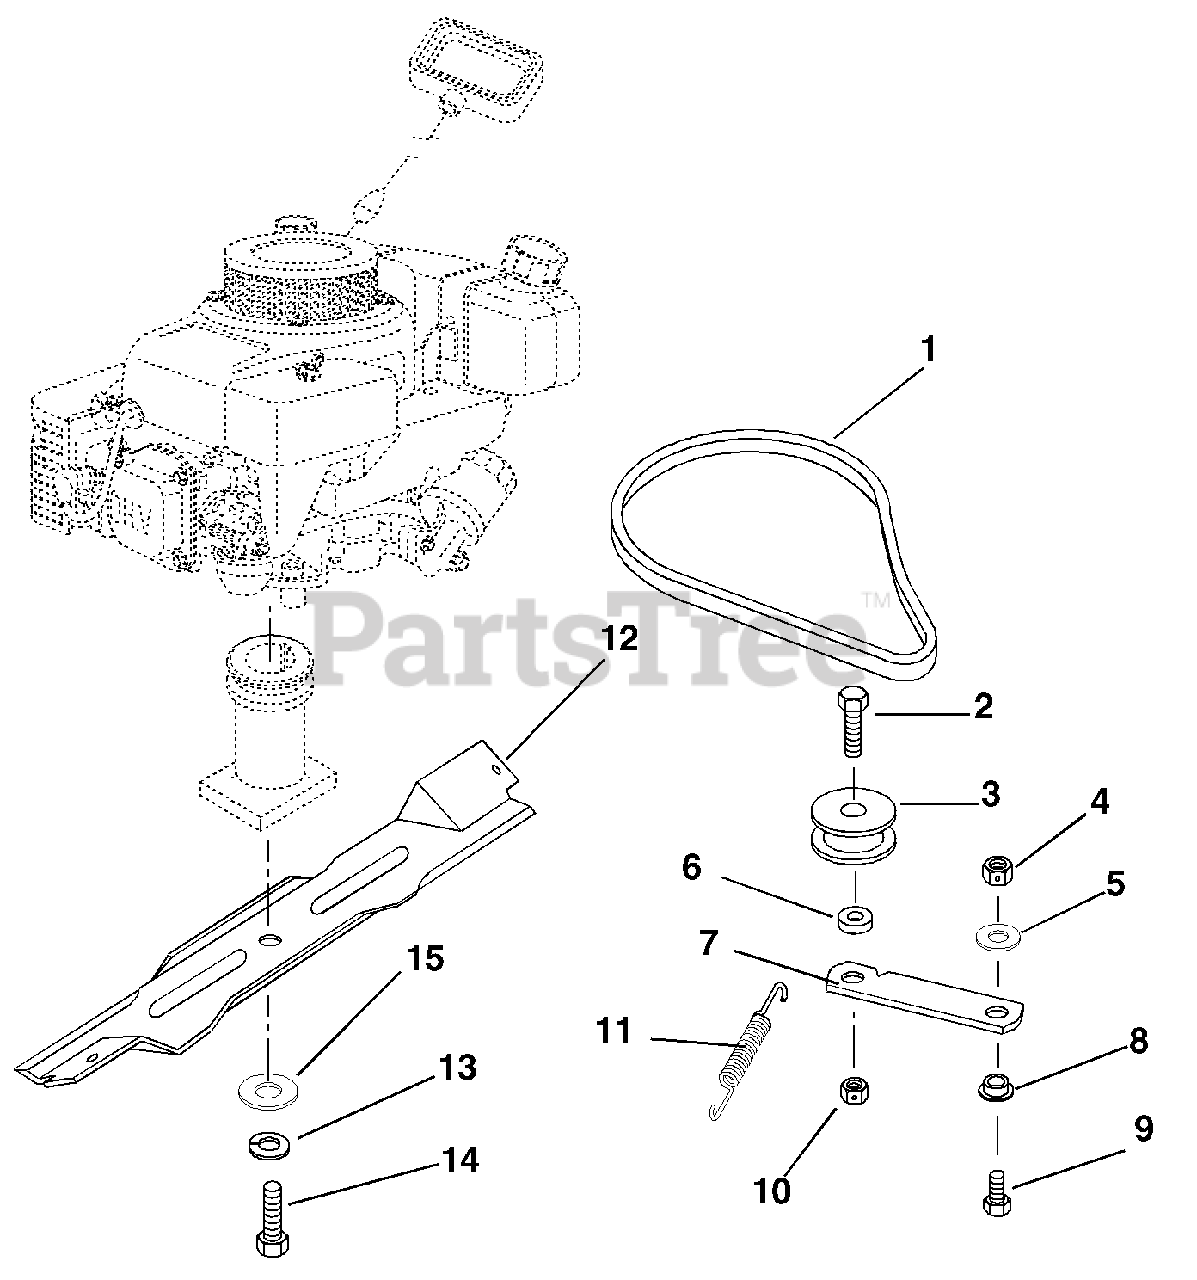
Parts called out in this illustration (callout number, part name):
1	V-BELT, 3L-COGGED
2	@BLT-HEX .44-14X1.25 GR5 YWZC
3	IDLER-FLAT 1.75 X .47
4	@NUT-LK-CTR .31-18 YWZC
5	WSHR-FL-STL .323X.625X.062 YWZ
6	SPACER .52 X .45 X .34
7	IDLER ARM
8	BSHG-FLG .325X.501X.250X1.120
9	@BLT-HEX .31-18X.75 GR5 YWZC
10	@NUT-LK-CTR .44-14 YWZC
11	SG-TENS .043X.44X3.31 WLD 5.8
12	BLADE LM 21 IN
13	@WSHR-LK .38X.094 REG YWZC
14	BLT-HEX .38-24 X 2.00 GR8 YWZC
15	WSHR-FL-STL .390X1.5X.125 YWZC
